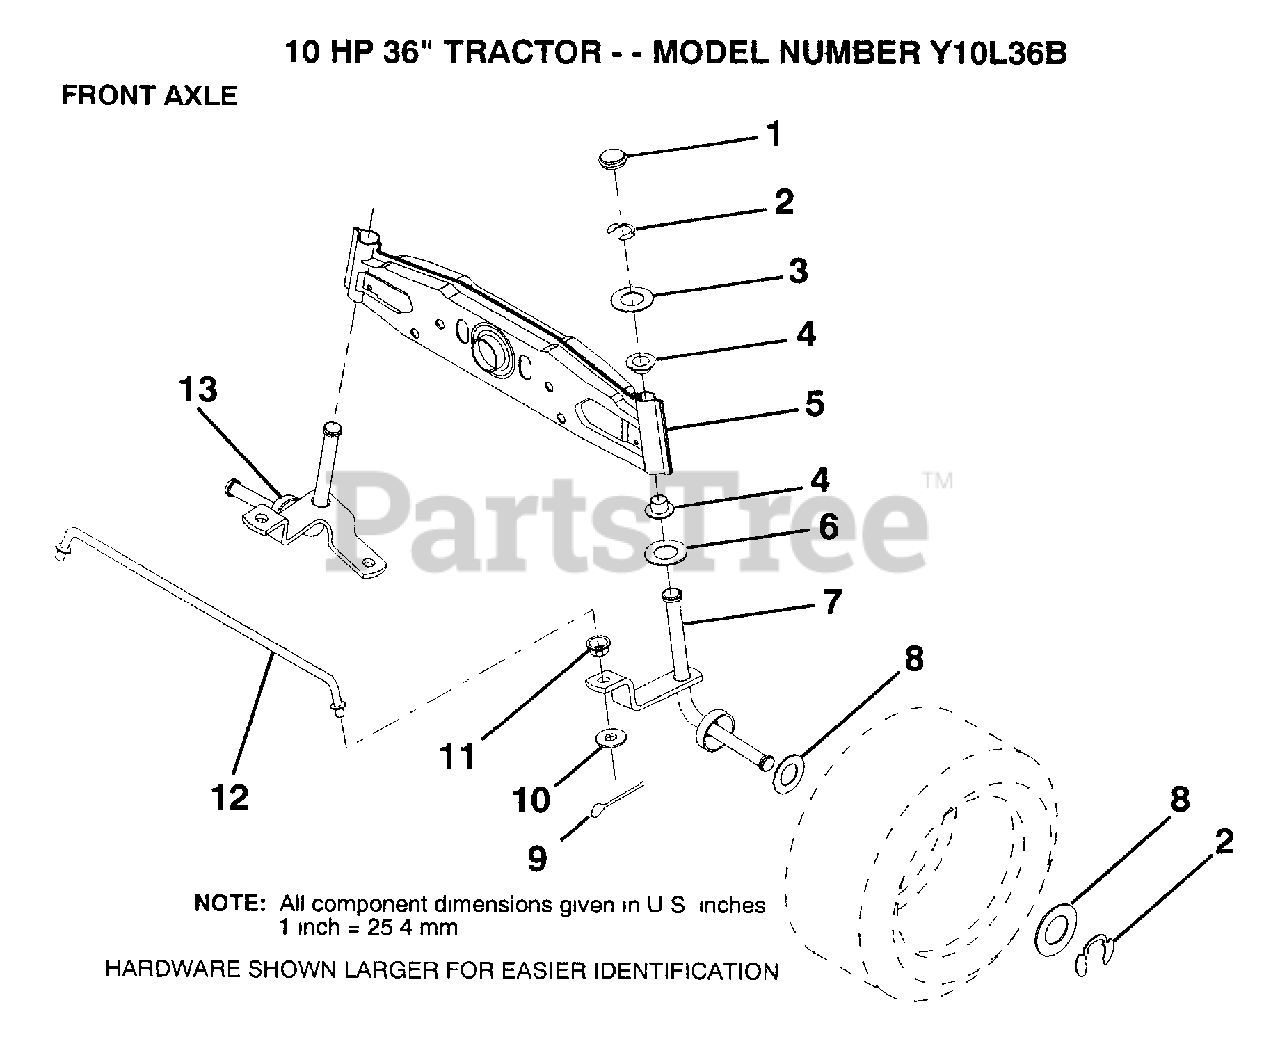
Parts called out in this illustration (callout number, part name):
1	CAP
2	RING
3	WASHER
4	NYLINER
5	AXLE FRONT
6	WASHER .T
7	SPINDLE RH
8	WASHER
9	COTTER PIN
10	WASHER
11	BUSHING.DRAGLINK
12	ROD TIE
13	SPINDLE LH
